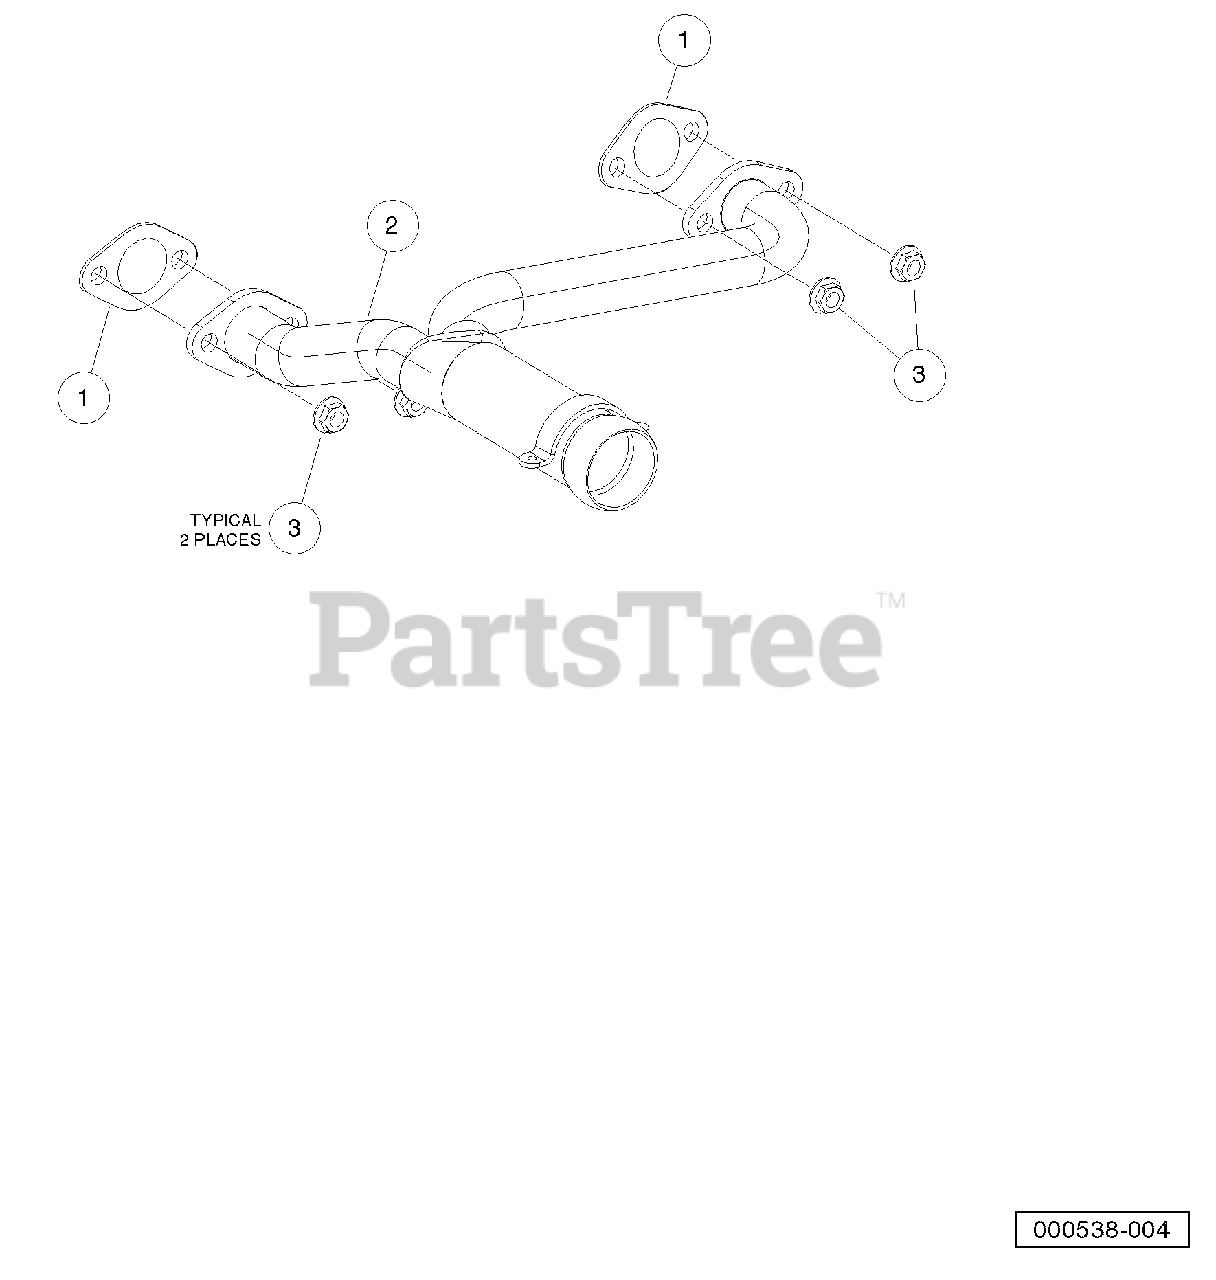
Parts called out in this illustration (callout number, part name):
1	Gasket, Exhaust Header, Fh680d
2	Header, Exhaust, Gas, Fh680d
3	Nut Flg, M8 X 1.25 Serrated
